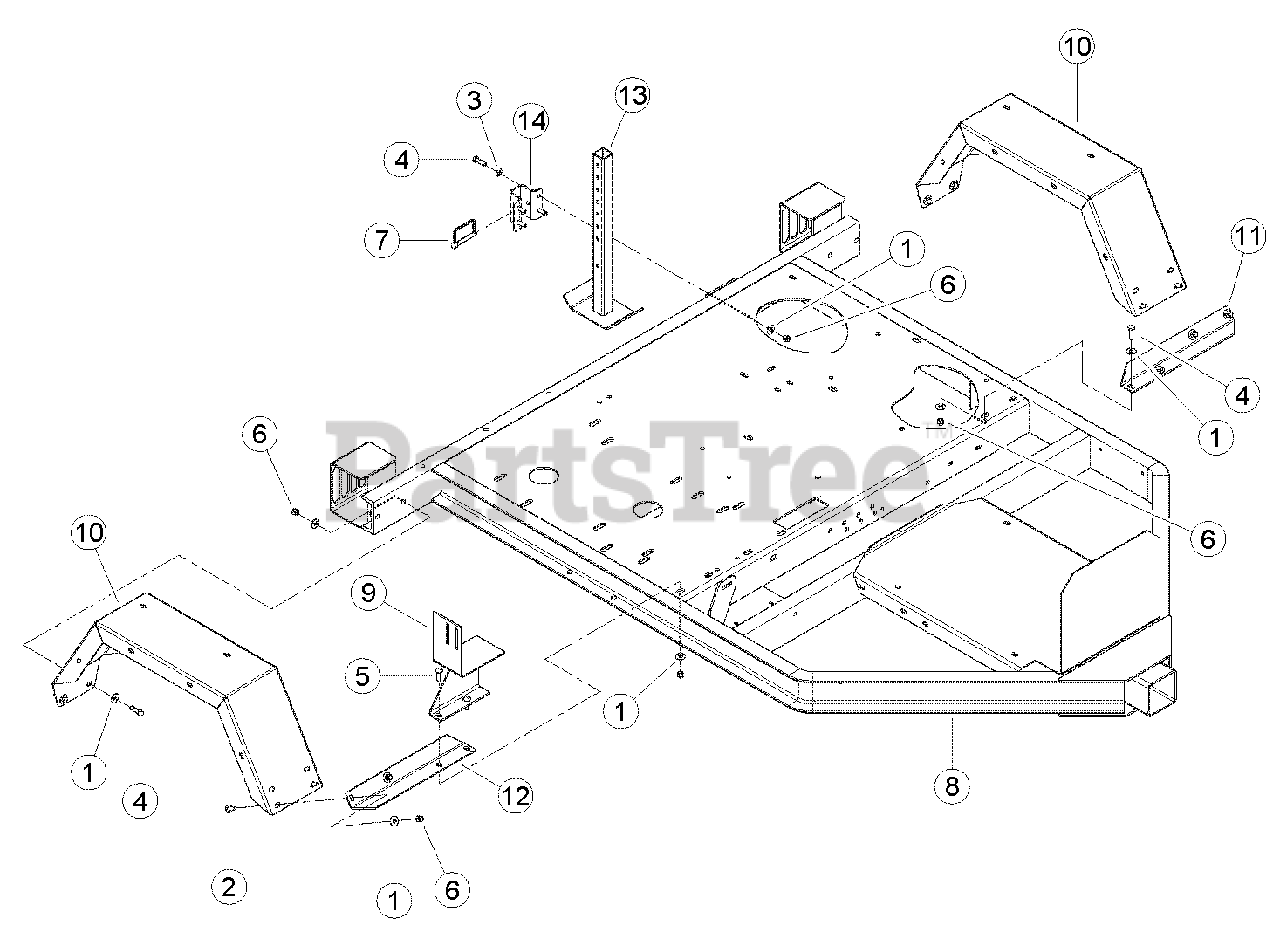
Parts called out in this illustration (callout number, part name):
1	WASHER, 3/8 FLAT ZP
2	BOLT, 3/8 X 1 CRG GR5 NC ZP
3	WASHER, 3/8 SAE FLAT ZP
4	BOLT, 3/8 X 1-1/4 HEX HD GR5 ZP
5	BOLT, 3/8 X 1-1/4 CRG GR5 NC ZP
6	NUT, 3/8 NE NYLOCK ZP
7	PIN, 3/8" X 2-3/4" SNAP
8	WELDMENT, CHIPPER TRAILER
9	WELDMENT, BELT GUIDE
10	FENDER, HEAVY DUTY
11	ANGLE, LH FENDER SUPPORT
12	ANGLE, RH FENDER SUPPORT
13	WELDMENT, REAR STABILIZER
14	GUIDE, TRAILER SUPPORT
